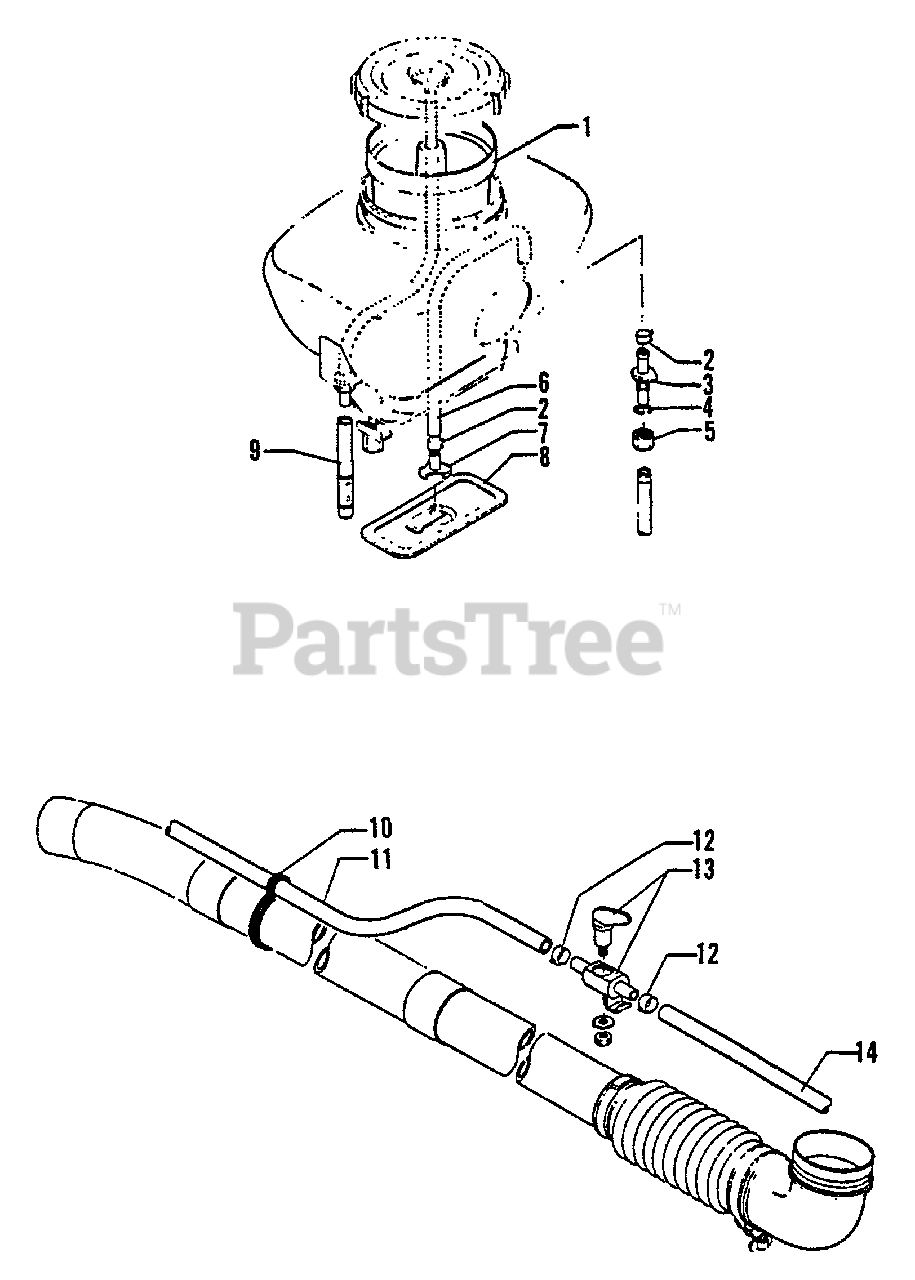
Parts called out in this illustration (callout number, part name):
1	FILTER, CHEMICAL TANK
2	CLIP - 13
3	CONNECTOR, PIPE
5	NUT, CONNECTOR
6	HOSE, FLUID
7	MOUTH, SUCTION
8	Plate, Base
9	HOSE, AIR
10	CLIP
11	PIPE - 720
12	CLIP - 13
13	VALVE ASSY
